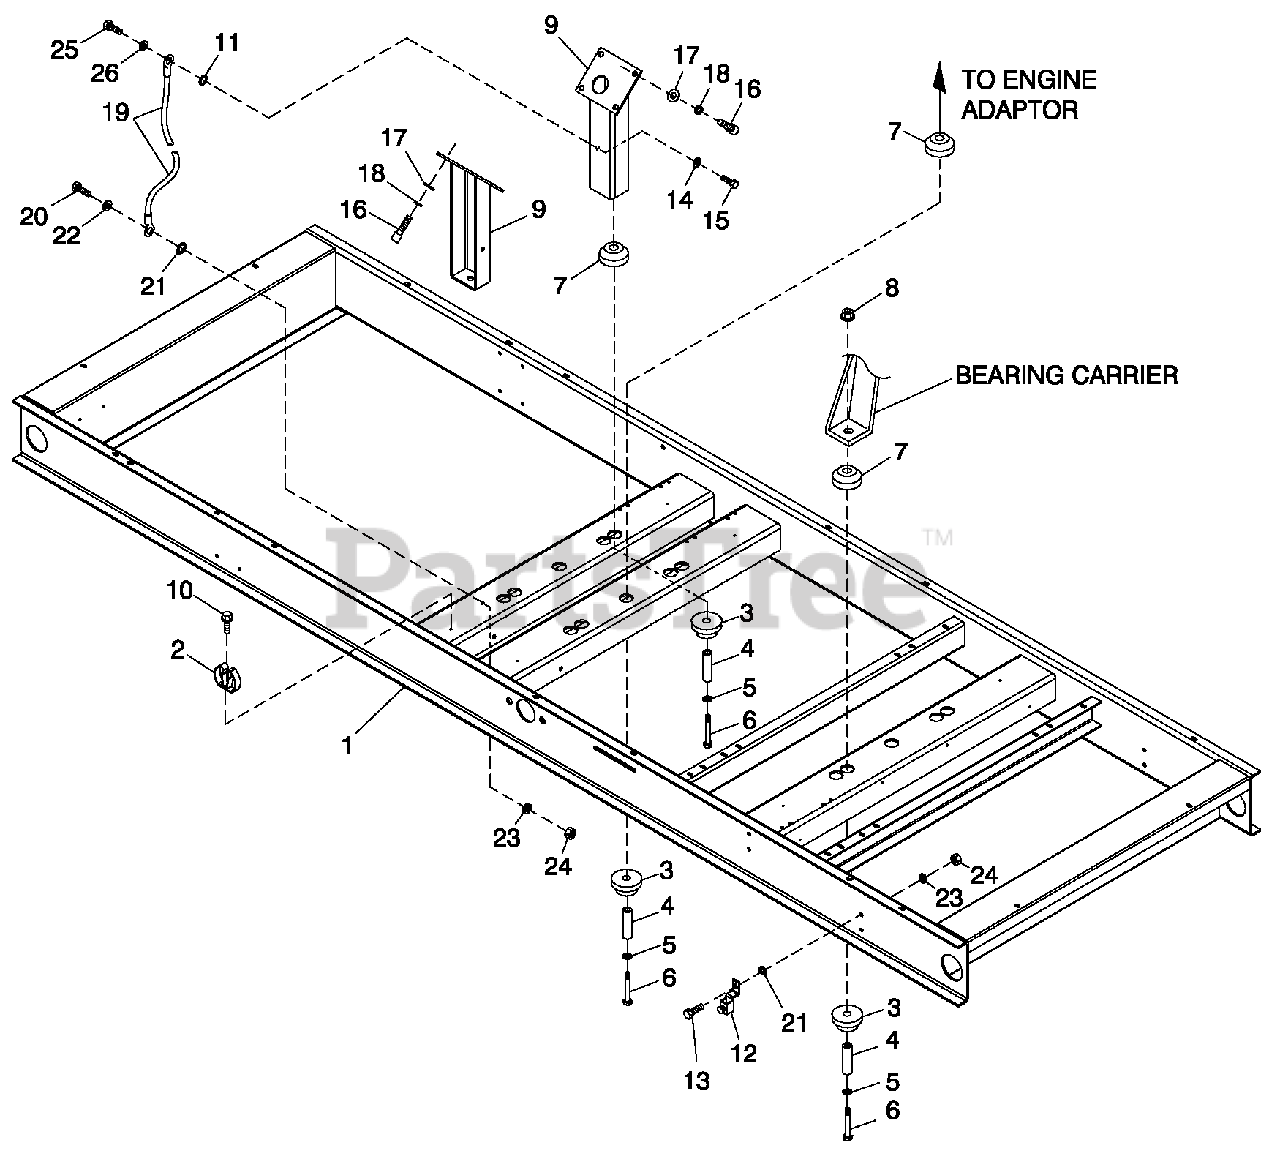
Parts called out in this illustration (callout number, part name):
1	MTG BASE CP 5.4L 100KW DD
2	SPRING CLIP HOLDER .37-.62
3	DAMPENER VIBRATION
4	SPACER .49 X .62 X 1.87 PWDR/ZINC
5	WASHER FLAT M12
6	SCREW HHC M12-1.75 X 85 G8.8
7	DAMPENER VIBRATION 50 WHITE
8	NUT LOCKING M12-1.75
9	SUPPORT ENG 5.4L LH/RH 6.8L RH
10	SCREW HHTT M4-0.7 X 8 BP
11	WASHER SHAKEPROOF INT 1/4
12	LUG SOLDERLESS 3/0-#4 X 13/32 CU
13	SCREW HHC M8-1.25 X 25 G8.8
14	WASHER FLAT 1/4-M6 ZINC
15	NUT HEX M6 X 1.0 G8 YEL CHR
16	SCREW SHC M10-1.5 X 30 G12.9
17	WASHER FLAT 3/8-M10 ZINC
18	WASHER LOCK M10
19	WIRE ASSEM #4GA GRD
20	SCREW HHC M8-1.25 X 30 G8.8
21	WASHER SHAKEPROOF INT 3/8
22	WASHER LOCK M8-5/16
23	WASHER FLAT 5/16-M8 ZINC
24	NUT HEX M8-1.25 G8 YEL CHR
25	SCREW HHC M6-1.0 X 30 G8.8
26	WASHER LOCK M6-1/4
